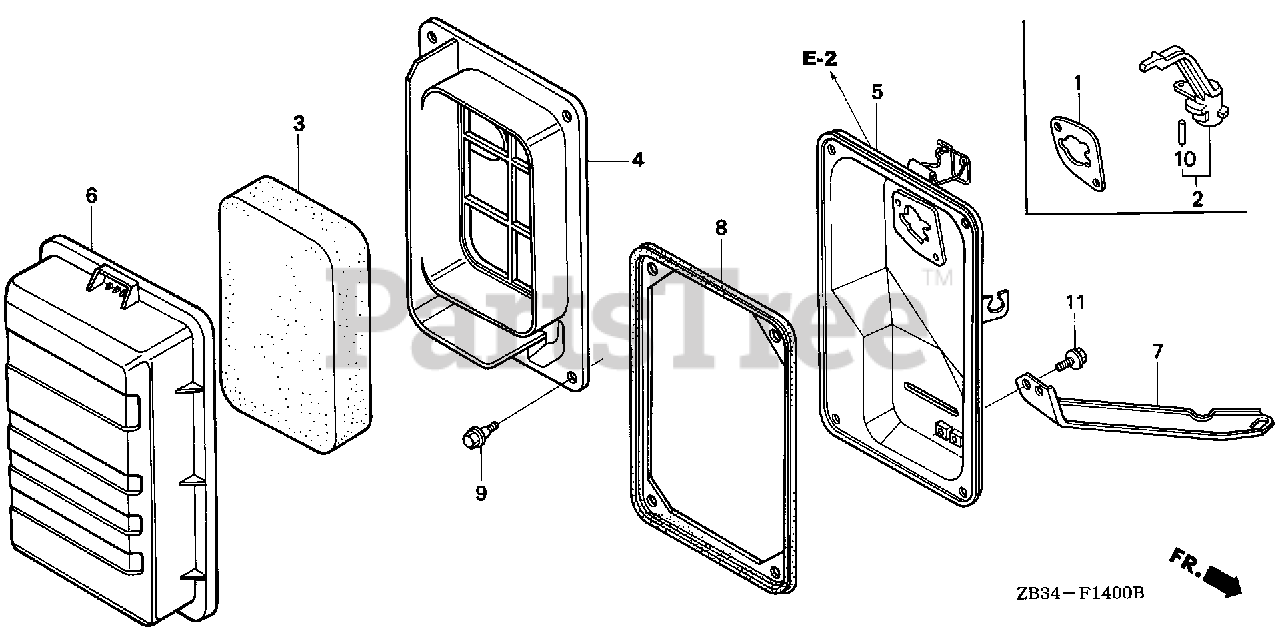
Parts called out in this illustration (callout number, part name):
1	GASKET, AIR CLEANER
2	LEVER, CHOKE
3	ELEMENT, AIR CLEANER
4	SEPARATOR, AIR CLEANER
5	HOUSING, AIR CLEANER
6	COVER, AIR CLEANER
7	STAY, AIR CLEANER
8	SEAL, AIR CLEANER
9	BOLT, TURN SIGNAL SETTING
10	PIN, SPRING (2X12)
11	BOLT, FLANGE (6X10)
